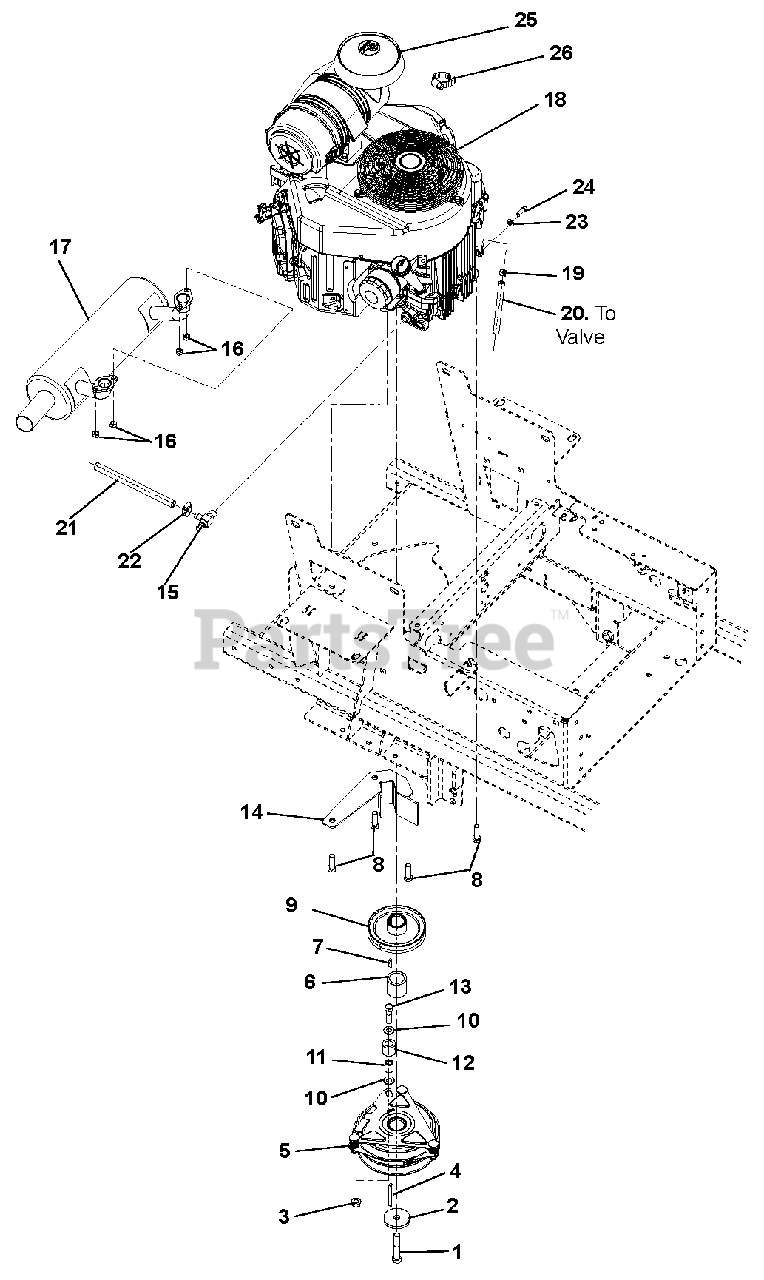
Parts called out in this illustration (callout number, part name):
1	Bolt, Hex .44-20 x 2.50
2	Washer, Flat Steel .469 x 2.00 x .25
3	Nut, Locking Top Flange .38-16
4	Key .25 x .25 x 2.25
5	Clutch, Ogura GT2.5-FE02
6	Spacer, 1.125 x 1.50 x 1.40
7	Key, Square .25 x .625 x .25 SAE 8630 or SAE 1035
8	Bolt, Hex .38-16 x 1.25 FTH
9	Sheave, 4.831 x 1.127
10	Washer, Flat Steel .406 x .812 x .065
11	Bushing, Sleeve .407 x .625 x .813 Steel
12	Bumper, Rubber .62 x 1.0 x .88 LG Engine
13	Bolt, Hex .38-16 x 1.50
14	100I Clutch Stop Weldment
15	Drain, .50 Oil
16	Nut, Locking Top M8-1.25
17	Muffler, Kawasaki FX (991079, 080, 081)
18	Engine, Kawasaki FX691 (991079, 080)
19	Clamp, Fuel Line
20	Hose, .25 Low-PERM Bulk Gas
21	Tube, Oil Drain 8" Clear Vinyl
22	Clamp, .88 Diameter Hose
23	Washer, Locking .31 x .078 Regular
24	Bolt, Hex M8-1.25 x 20
25	Cap, Air Cleaner Rain
26	Clamp, Hose 2.75 Dia. Worm
NS	Lead, Starter Solenoid
NS	Air, Filter Element, Outer Primary
NS	Air, Filter Element, Inner Safety
NS	Filter, Oil – Kawasaki # 49065-2078
NS	Plug, Spark – Kawasaki # 92070-7004
NS	Filter, Fuel – Kawasaki # 49019-7001
